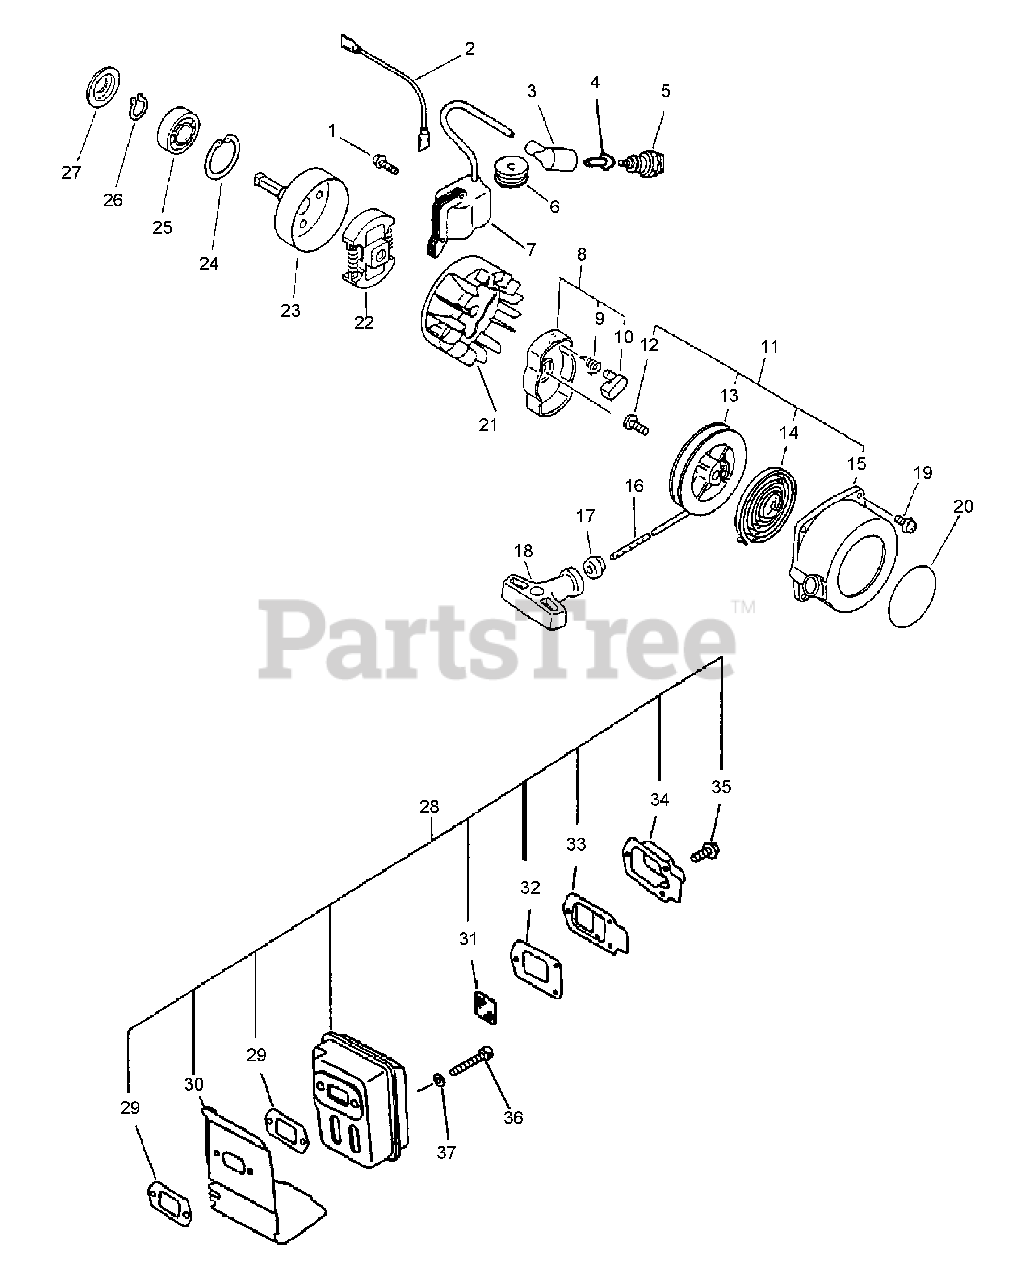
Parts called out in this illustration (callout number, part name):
1	SCREW - 4X22
2	LEAD - IGNITION
3	CAP, SPARK PLUG
4	TERMINAL, SPARK PLUG CAP
5	SPARK PLUG -- BPM-7Y
5	SPARK PLUG -- BPMR-7A
6	GROMMET
7	COIL, IGNITION
8	STARTER PAWL ASSY
9	SPRING, RETURN
10	PAWL, STARTER - BLACK
11	STARTER ASSY
13	REEL, ROPE
14	SPRING, REWIND
15	CASE, STARTER
16	ROPE, STARTER - 3X1000
17	GUIDE, ROPE
18	GRIP, STARTER
19	SCREW - 4X16
20	LABEL - ECHO
21	FLYWHEEL
22	CLUTCH ASSY
23	DRUM, CLUTCH
24	RING, RETAINING - 32
25	BEARING, BALL - 6201
26	RING, RETAINING - 12
27	RETAINER, PIPE
28	MUFFLER ASSY
29	GASKET, EXHAUST
30	COVER, EXHAUST
31	SCREEN, SPARK ARRESTOR
32	GASKET, EXHAUST
33	GASKET, EXHAUST - INNER
34	GUIDE, EXHAUST - OUTER
35	SCREW - 4X10
36	SCREW - 5X55
37	WASHER - 5
